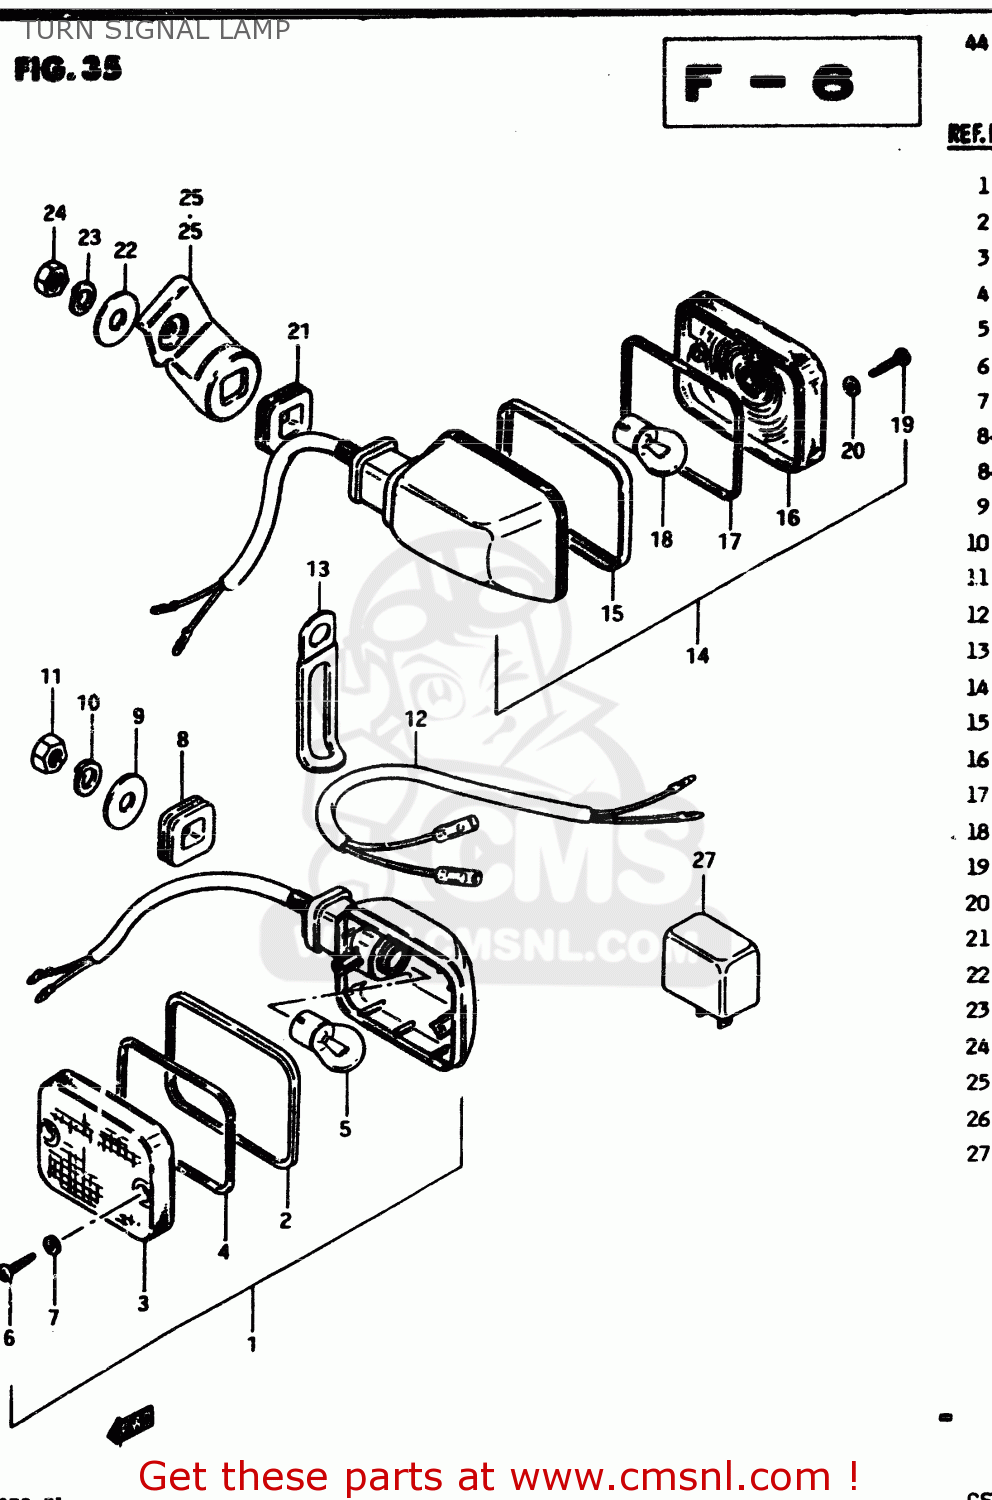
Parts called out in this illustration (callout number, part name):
1	LAMP ASSEMBLY,FRONT TURN SIGNAL
2	RIM
3	LENS
4	GASKET (NAS)
5	BULB(12V23W,STANLEY,A4577A)
6	SCREW
7	GASKET (NAS)
8	CUSHION
9	WASHER (10.5X30X2.3)
10	LOCK WASHER
11	NUT
12	LEAD WIRE, TURN SIGNAL LAMP
13	CLAMP
14	LAMP ASSEMBLY,FRONT TURN SIGNAL
15	RIM
16	LENS
17	GASKET (NAS)
18	BULB(12V23W,STANLEY,A4577A)
19	SCREW
20	GASKET (NAS)
21	CUSHION
22	WASHER (10.5X30X2.3)
23	LOCK WASHER
24	NUT
25	BRACKET,REAR TURN SIGNAL
26	BRACKET,REAR TURN SIGNAL
27	RELAY,TURN SIGNAL
